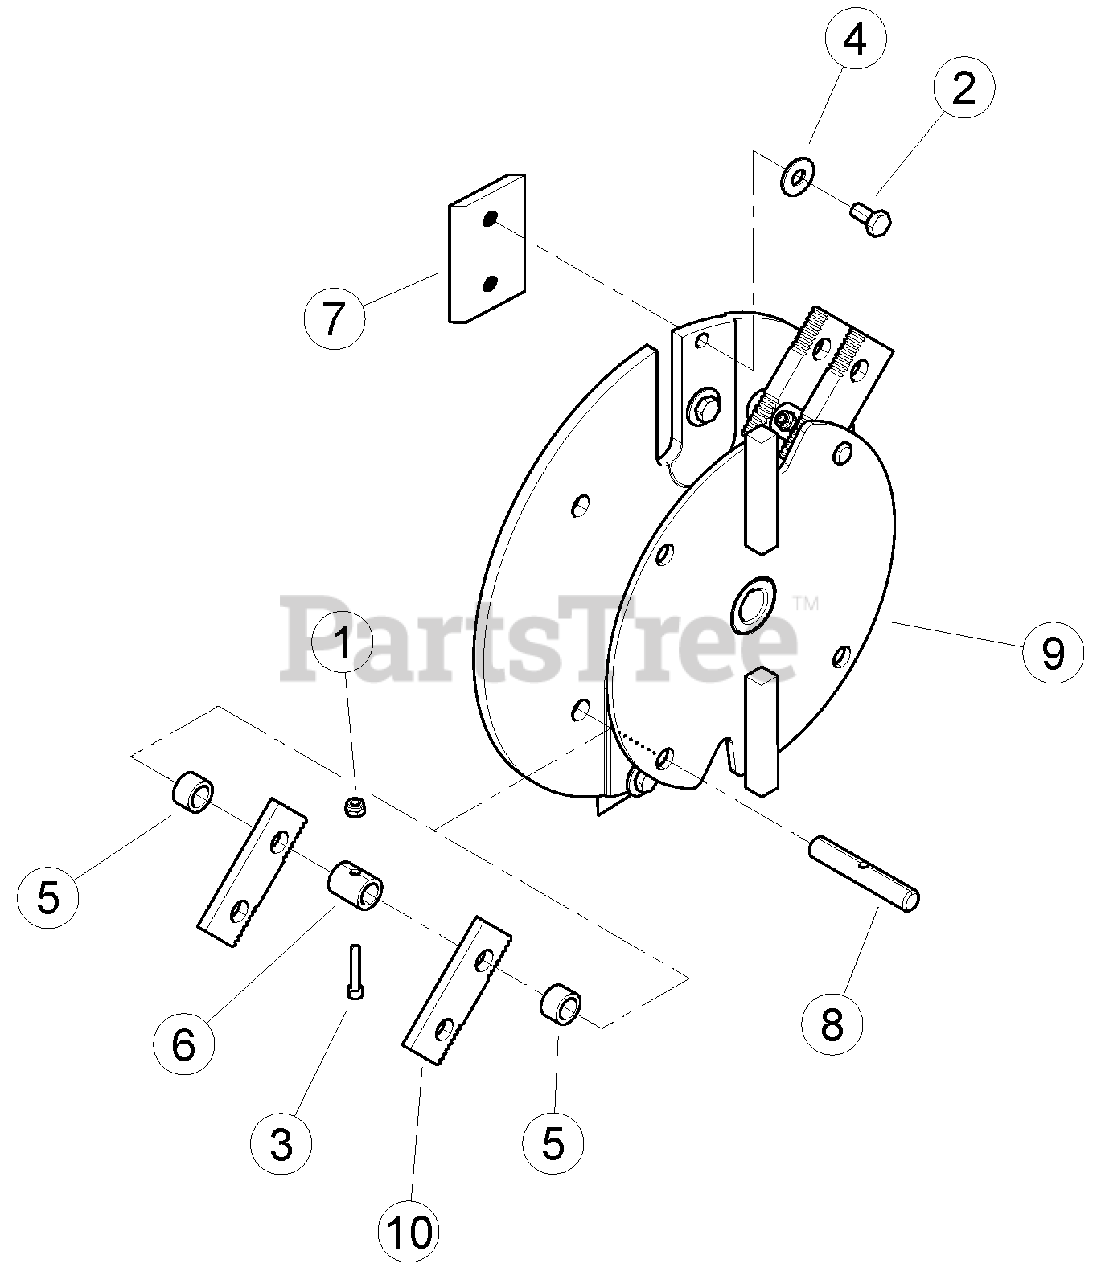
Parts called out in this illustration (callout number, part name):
1	NUT, 10/24 NYLOCK TYPE NM ZP
2	BOLT, 5/16-18 X 5/8 HEX GR8 PATCH Z
3	CAP SCREW, #10-24 X 1-1/8 PL SKT HD
4	WASHER, 5/16 GR8 USS FLAT
5	SPACER, .75 X .47
6	SPACER, .75 X .90 W/ HOLE
7	KIT, TOOL STEEL BLADE
8	SHAFT, SHREDDER
9	WELDMENT, S/C ROTOR
10	KIT, SC2170 SHREDDER KNIVES STANDARD
